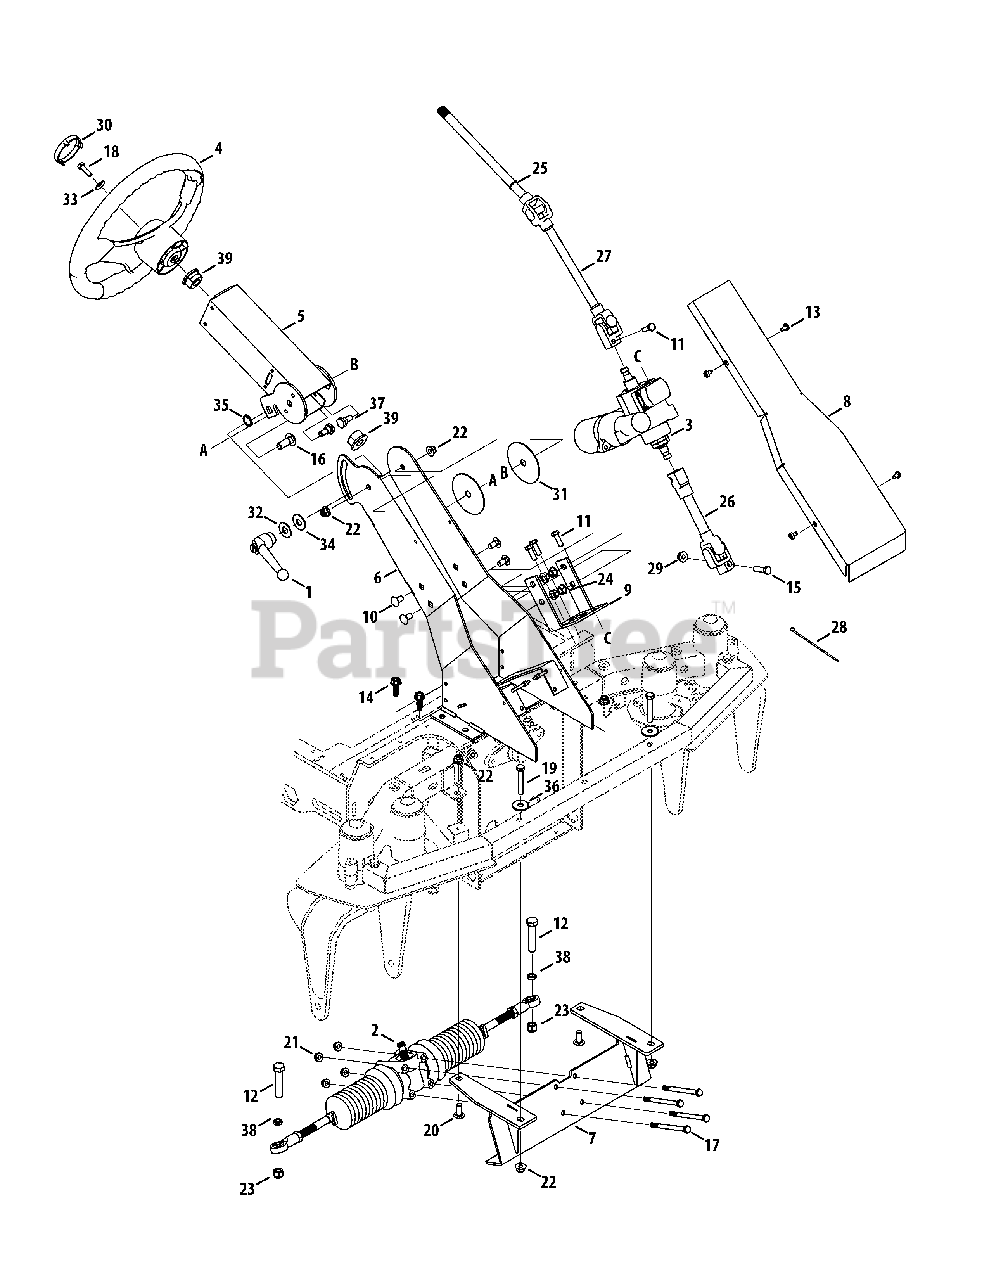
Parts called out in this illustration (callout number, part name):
1	Steering Column Adjustment Lever
2	Steering Gearbox
3	Power Steering Arm
3	Module, EPS Control
4	Steering Wheel
5	Upper Column
6	Base Column
7	Steering Rack Mount
8	Front Column Cover
9	Power Steering Mount
10	Carriage Bolt, 3/8-16 x .750
11	Hex Cap Screw, M8-1.25 x 25.0
12	Hex Cap Screw, 1/2-20 x 2.25
13	Screw, 1/4-20 x .500
14	Screw, 3/8-16 x 1.00
15	Hex Cap Screw, 3/8-16 x 1.50
16	Carriage Bolt, 1/2-13 x 1.25
17	Hex Cap Screw, 5/16-18 x 4.00
18	Hex Cap Screw, 5/16-18 x 1.00
19	Hex Cap Screw, 3/8-16 x 2.50
20	Carriage Bolt, 3/8-16 x 1.00
21	Nut, 5/16-18, Flangelock
22	Nut, 3/8-16, Flnagelock
23	Nut, 1/2-20, Hexlock
24	Nut, 3/8-16, Flangelock
25	Retainer Ring, .625
26	Steering Shaft, Bottom
27	Steering Shaft, Top
28	Cable Tie
29	Nut, Hex Lock, 3/8-16
30	Cap, No Sprig
31	Column Wear Plate
32	Washer, .531 x 1.25 x .100
33	Bevel Washer, .340 x .872 x .060
34	Washer, .640 x 1.25 x .050
35	Lock Washer, 17 x 23.8 x 1.95
36	Washer, .406 x 1.00 x .105
37	Shoulder Bolt, .496 x .336, 3/8-16
38	Spacer, .515 x .75 x .220
39	Flange Bearing, .63 x 1.15
